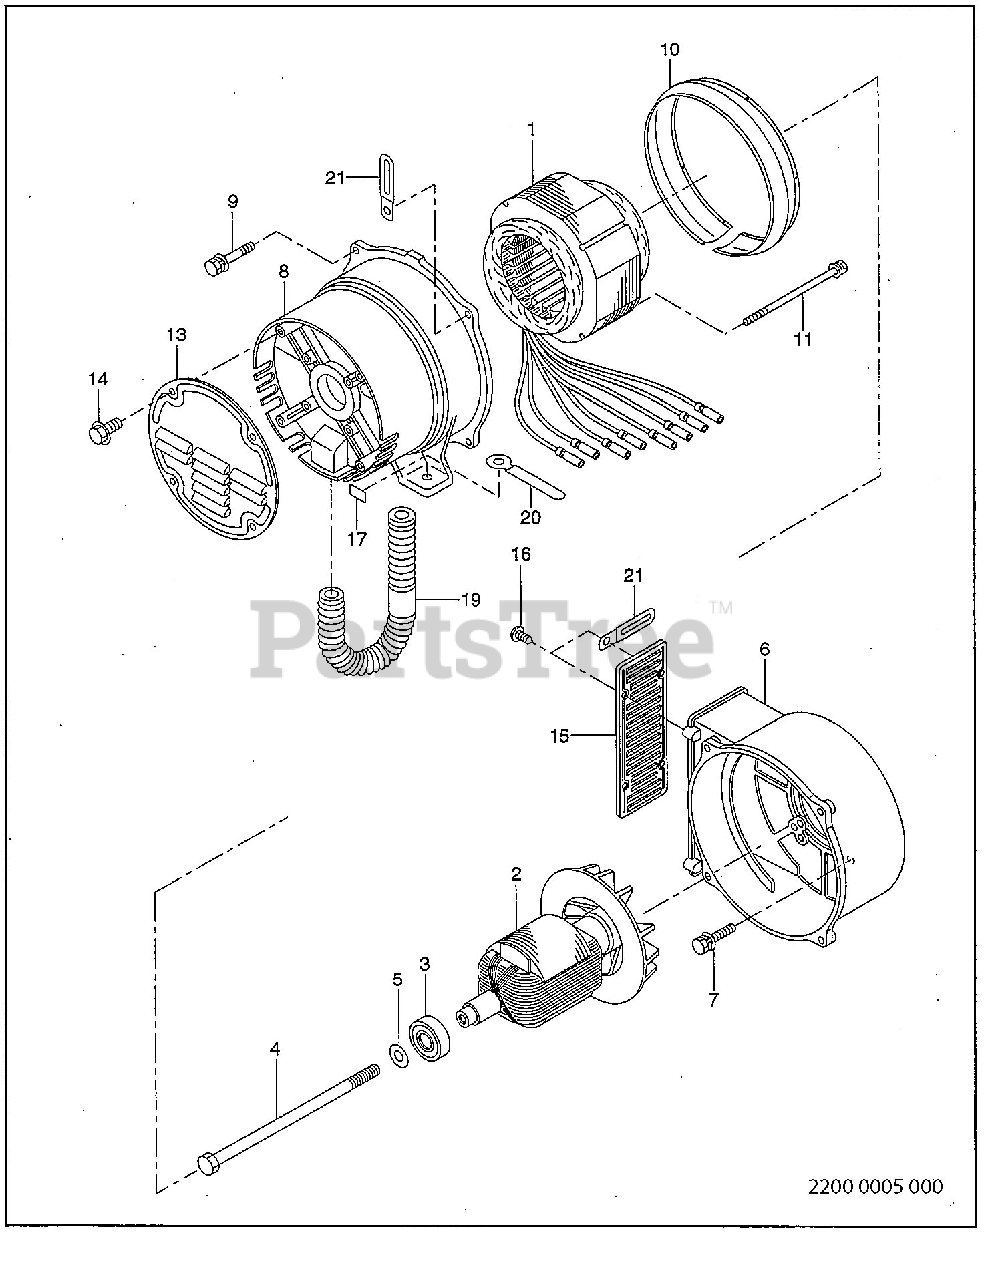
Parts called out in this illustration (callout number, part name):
1	STATOR ASSY
2	ROTOR ASSY
3	BALL BEARING (6203ZZ)
4	THROUGHT BOLT
7	BOLT and WASHER ASSY
8	REAR COVER ASSY
9	BOLT and WASHER ASSY
11	BOLT and WASHER ASSY
15	FRONT PROTECTOR
17	LABEL (GROUND)
